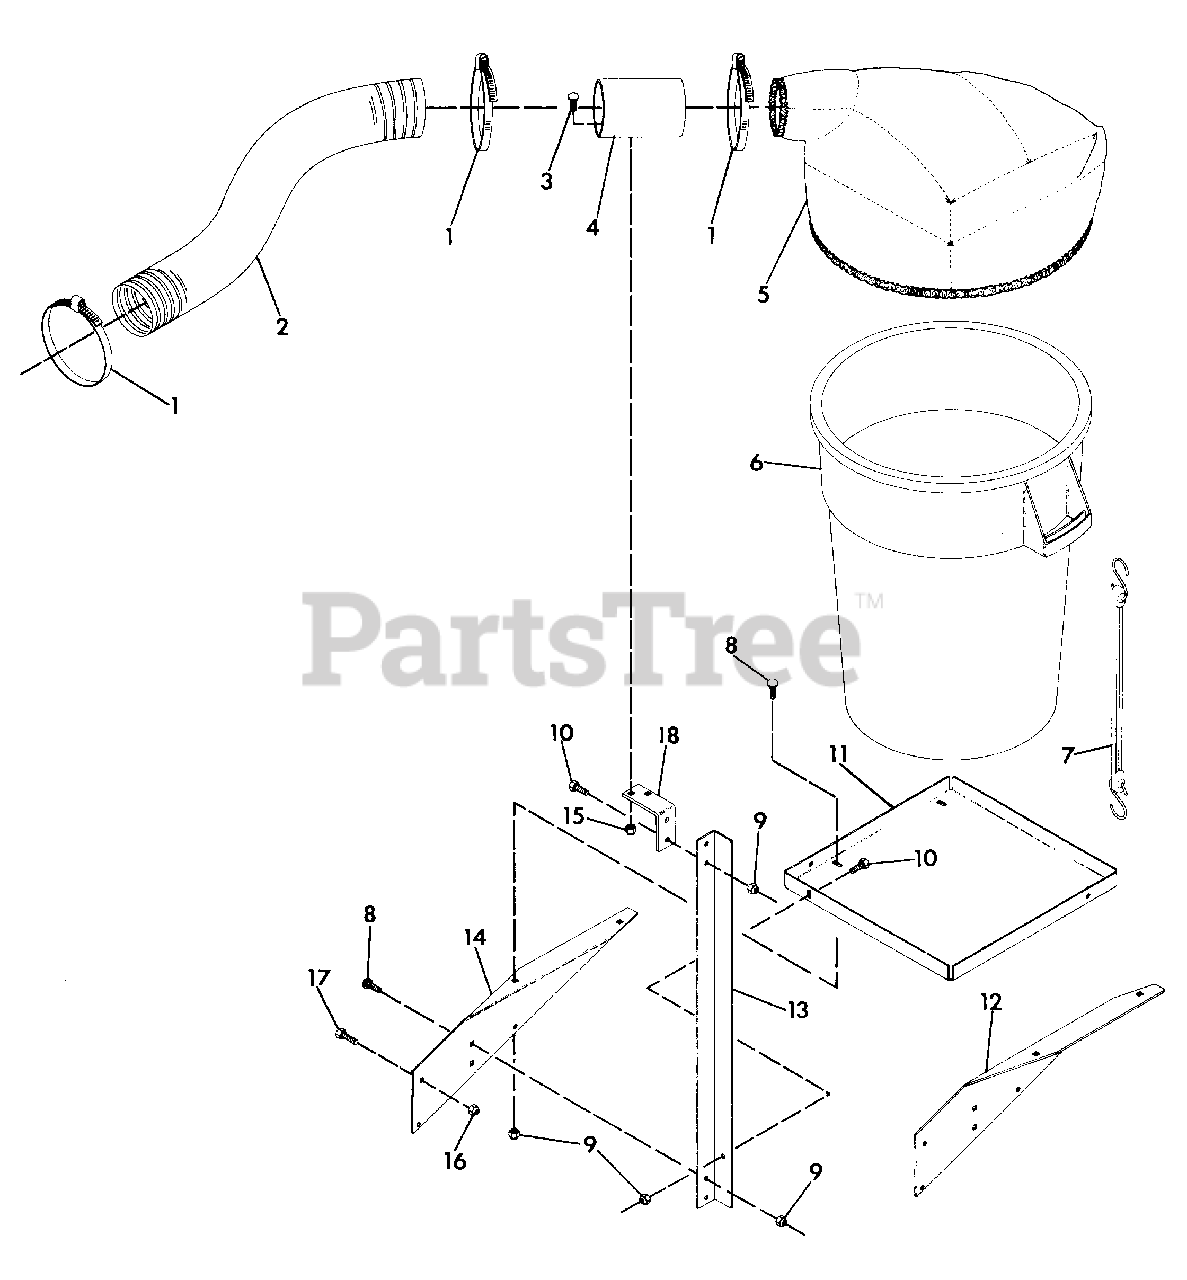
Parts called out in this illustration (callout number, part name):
1	CLAMP
2	HOSE, BLOWER TO CAN
3	BOLT, 5/16-18X.625 RD HD SQ NK
4	TUBE, CONNECTOR
5	COVER, TOP
6	CAN, GRASS
7	STRAP, HOLD DOWN
8	BOLT, 3/8-16X1 RD HD SQ NK
9	NUT, LOCK 3/8-16
10	BOLT, HEX 3/8-16X1
11	TRAY, SUPPORT
12	RAIL, LEFT SIDE
13	SUPPORT, TUBE
14	RAIL, RIGHT SIDE
15	NUT, LOCK 5/16-18
16	NUT, LOCK 1/2-13
17	BOLT, HEX 1/2-13X1.25
18	BRACKET, TUBE
